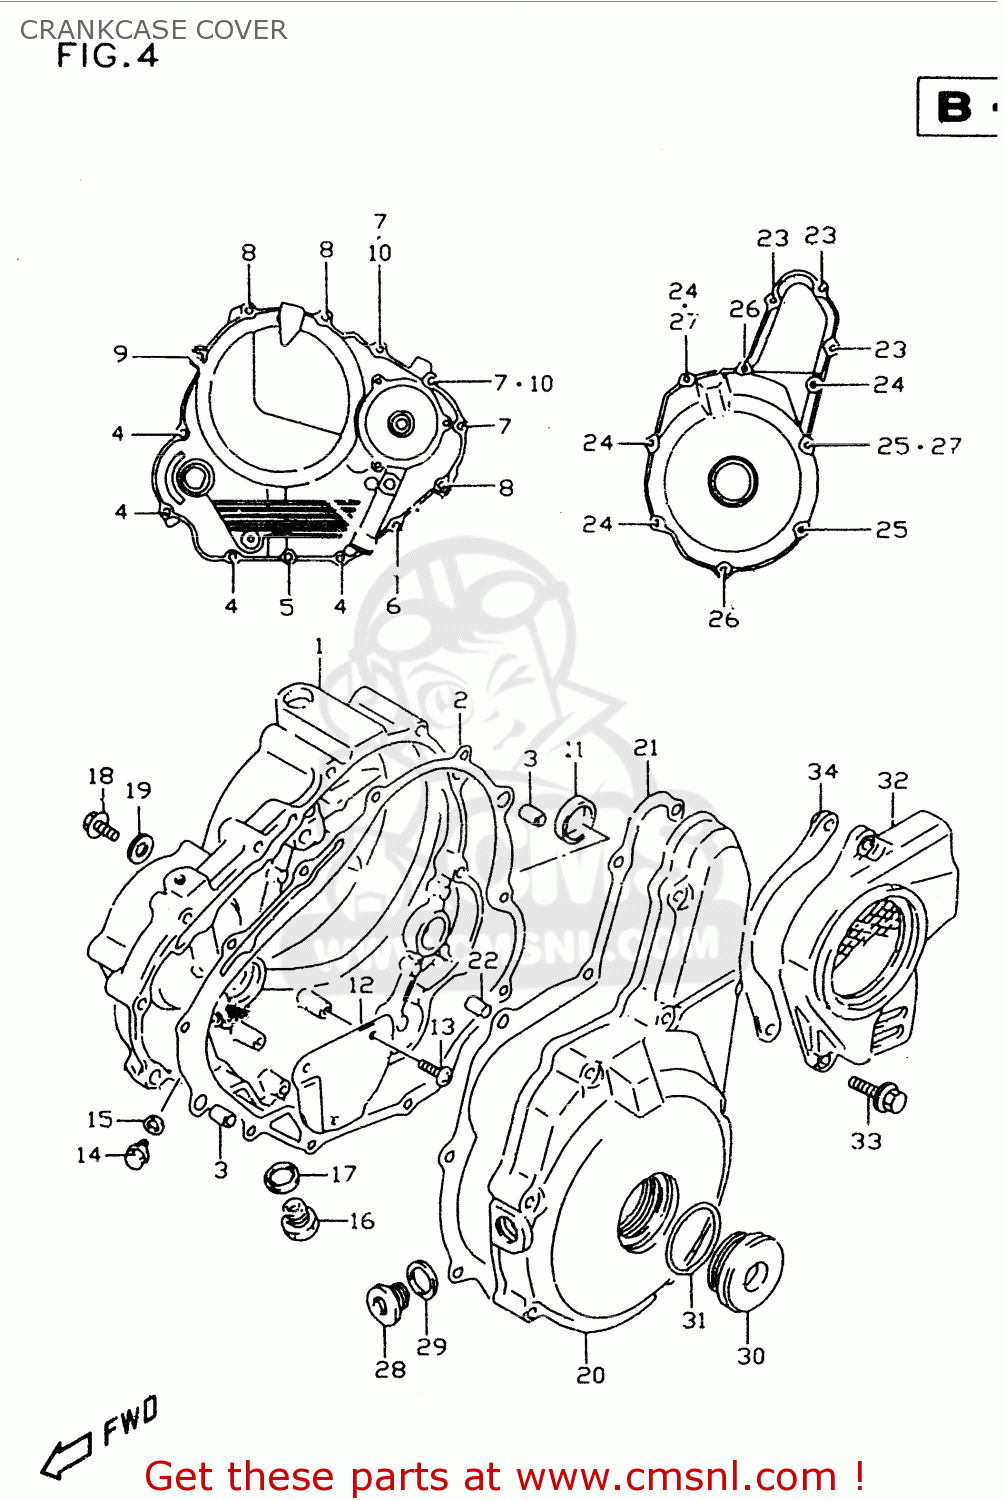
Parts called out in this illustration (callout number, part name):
1	COVER,CLUTCH
2	GASKET,CLUTCH COVER (NAS)
3	PIN
4	SCREW
5	BOLT,G/S SWITC
6	BOLT
7	BOLT
8	BOLT
9	BOLT
10	GASKET(5.8X11X1.2) (NAS)
11	PLUG,CLUTCH COVER KICK
12	SEPARATOR,OIL RETURN
13	SCREW
14	BOLT(6X8)
15	GASKET(6.2X11X1).2 (NAS)
16	PLUG(10X6.8)
17	GASKET(10X14X3.6) (NAS)
18	SCREW (6X10)
19	GASKET(5.8X11X1.2) (NAS)
20	COVER,MAGNETO
21	GASKET,MAGNETO COVER (NAS)
22	PIN
23	SCREW
24	BOLT
25	BOLT
26	BOLT
27	GASKET(5.8X11X1.2) (NAS)
28	PLUG,14X12
29	GASKET(13.8X18.8X4.8) (NAS)
30	PLUG(SILVER)
31	O RING(D:3.1,ID:32.7)
32	COVER,ENGINE SPROCKET
33	SCREW
34	PLATE,FR CHAIN GUIDE
